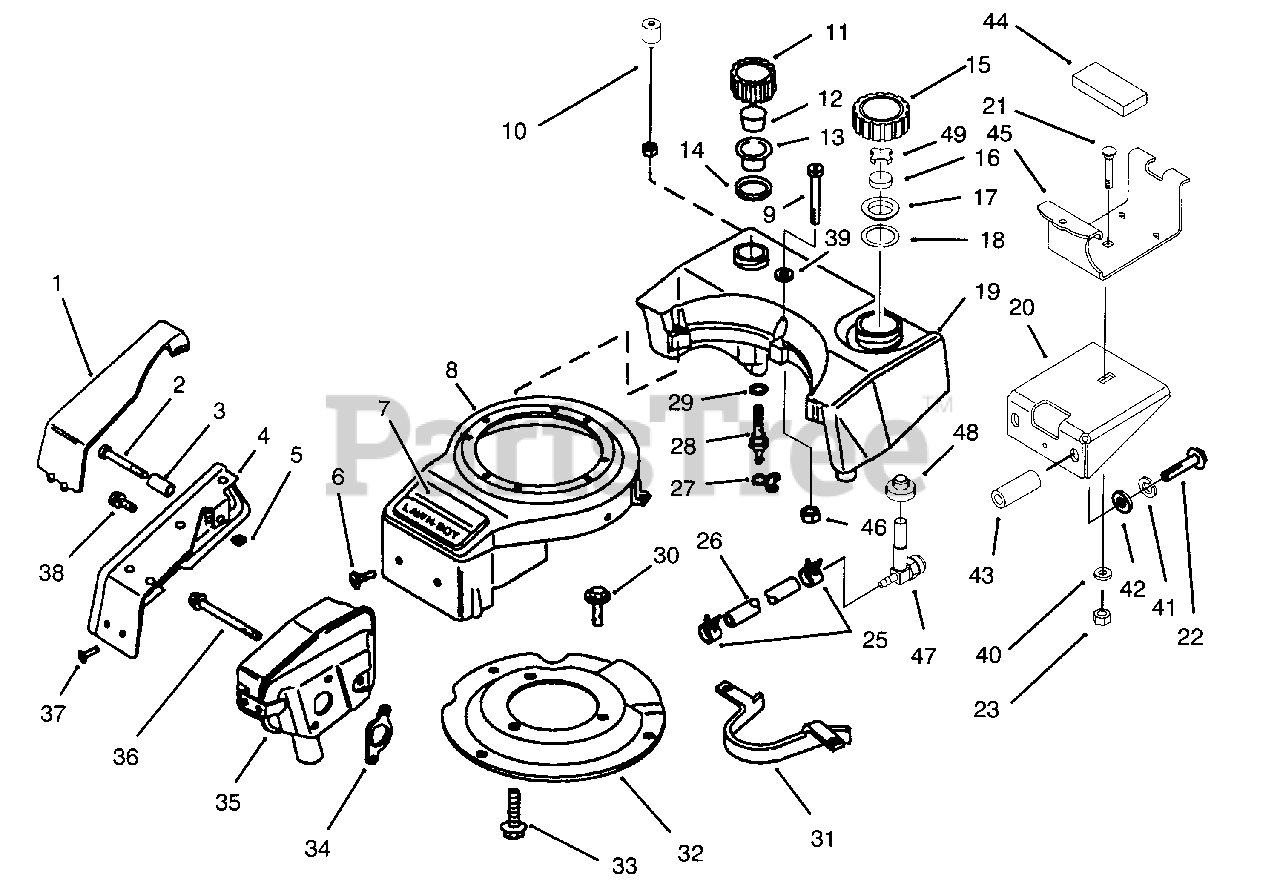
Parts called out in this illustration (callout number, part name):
1	Cover-Muffler
2	Screw-Muffler Guard
3	Spacer-Muffler Guard
4	Assembly-Muffler Guard (Incl. Ref. No. 1 & 5)
5	Pushnut
6	Screw-Shroud
7	Applique
8	Assy.-Shroud (Incl. Ref. No. 7)
9	Screw-Fuel Tank
10	Switch-Low Oil
11	Assembly-Oil Cap (Incl. Ref. No 12-14)
13	Cover-Baffle
15	Assembly-Fuel Cap (Incl. Ref. No.16- 18)
17	Cover-Baffle
19	Assembly-Fuel/Oil Tank
20	Bracket-Fuel Tank
21	Bolt-Carriage
22	Screw-Bracket To Engine
25	Clamp-Fuel Line
26	Fuel Line
27	Clamp-Oil Hose
28	Assembly-Oil Fitting (Incl. Ref. No.29)
30	Screw-Mtg Plate/Hsg.
31	Snubber-Belt
32	Plate-Engine Mounting
33	Screw-Mtg Plate To Eng.
34	Gasket-Exhaust
35	Muffler
36	Screw-Muffler
37	Screw-Muffler Guard
38	Screw-Muffler Guard
39	Washer-Flat
40	Washer-Flat
41	Washer-Lock
42	Washer-Flat
44	Mount-Fuel Tank
45	Saddle-Fuel Tank
46	Nut-Lock
48	Bushing
